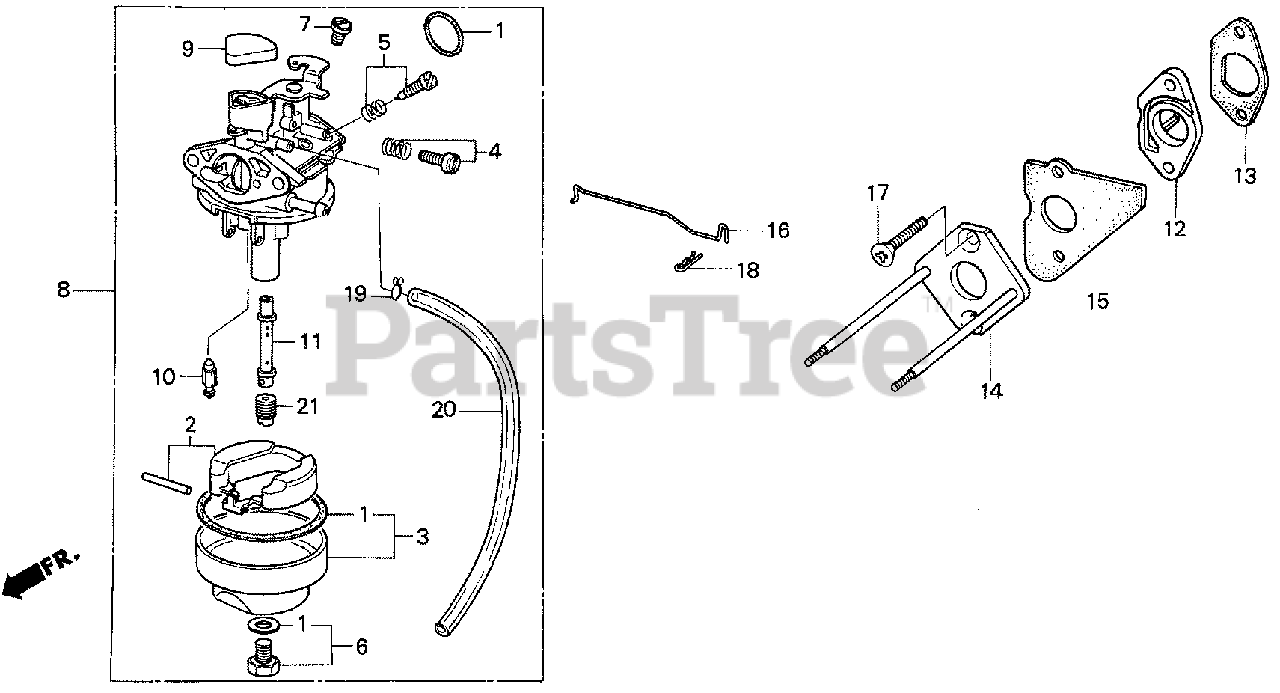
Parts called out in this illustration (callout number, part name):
1	GASKET SET
3	CHAMBER SET, FLOAT
4	SCREW SET A
4	SCREW SET A (NOT AVAILABLE)
5	SCREW SET A
6	SCREW SET
7	SCREW, PLUG (NOT AVAILABLE)
7	SCREW, PLUG
8	CARBURETOR ASSY. (NOT AVAILABLE)
9	CAP, DUST (CHOKE) (NOT AVAILABLE)
10	VALVE, FLOAT
11	NOZZLE, MAIN
12	INSULATOR, CARBURETOR
13	GASKET, INSULATOR
14	PLATE, CARBURETOR JOINT (NOT AVAILABLE)
15	GASKET, INSULATOR (NOT AVAILABLE)
16	ROD, AUTOMATIC CHOKE
17	SCREW, FLAT (3X6)
18	PIN, LOCK (4MM)
19	CLIP, TUBE (B7)
20	BULK HOSE, VINYL (4X7X8000) (4X7X210)
21	JET, MAIN (#50) Use from Engine SN BB07A B.
21	JET, MAIN (#52) Use from Engine SN BB07A B.
21	JET, MAIN (#55)
